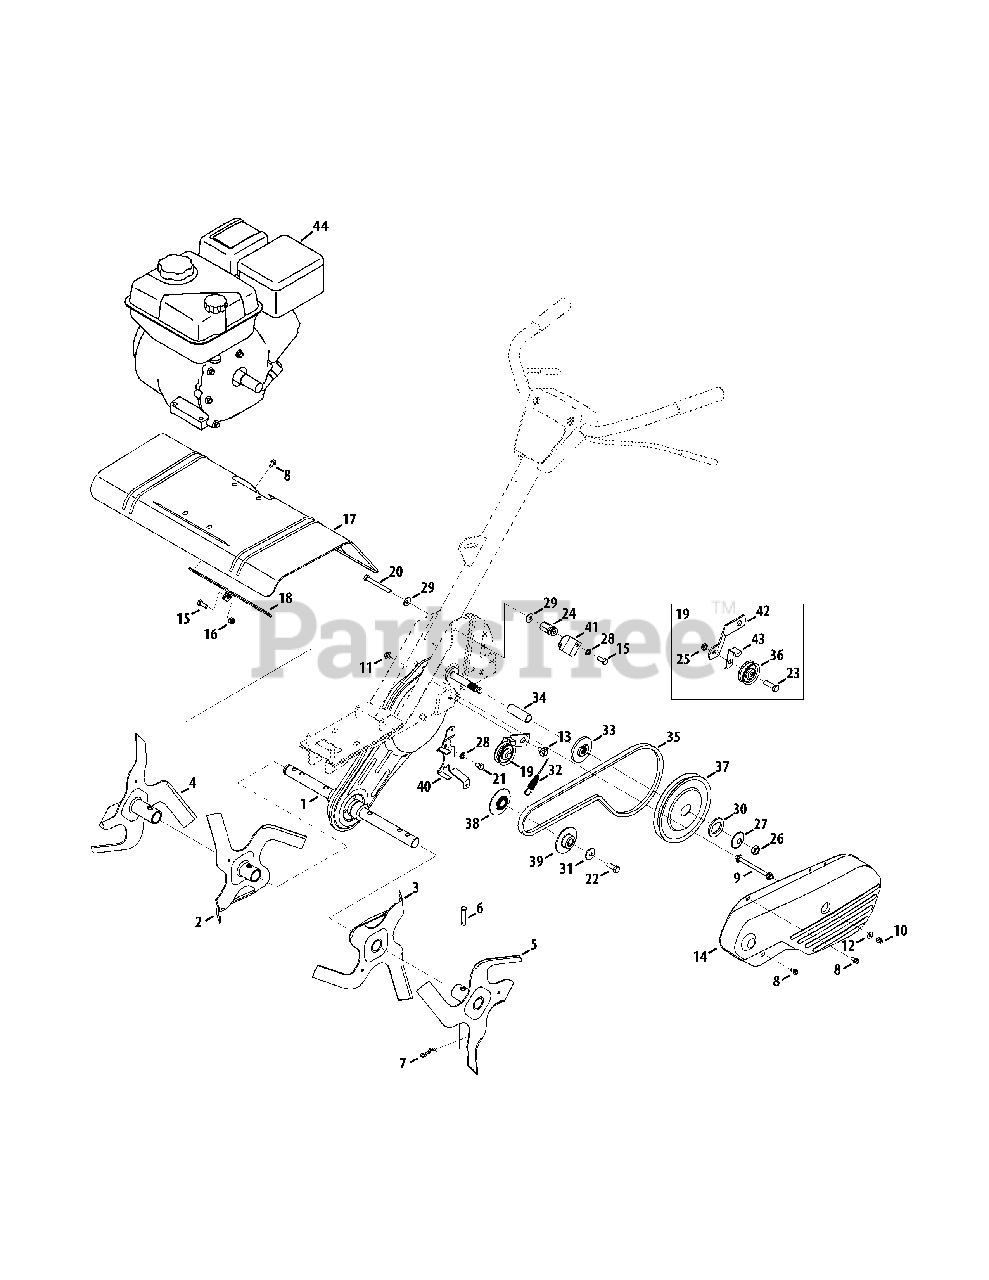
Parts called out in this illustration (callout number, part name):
1	Chain Case Assembly
2	Inner Tine Assembly, RH
3	Inner Tine Assembly, LH
4	Outer Tine Assembly, RH
5	Outer Tine Assembly, LH
6	Clevis Pin, .375 x 1.75
7	Bow Tie Cotter Pin
8	Screw, 1/4-20 x 0.500
9	Bolt, Belt Cover
10	Nut, 1/4-28, Lock
11	Nut, 5/16-18, Flange Lock
12	Flat Washer, .271 x .630 x .065
13	Shoulder Screw, .560 x .165 5/16-18
14	Belt Cover
15	Hex Head Screw, 5/16-18 x .75
16	Nut, 5/16-18, Flange Lock
17	Tine Shield
18	Bracket, Tine Shield
19	Idler Bracket Assembly
20	Hex Head Screw, 5/16-18 x 3.00
21	Hex Head Screw, 5/16-24 x .625
22	Hex Head Screw, 3/8-24 x 1.00
23	Hex Head Screw, 3/8-16 x 1.25
24	Hex Nut, 5/16-18
25	Jamlock Nut, 3/8-16
26	Nut, 1/2-20, Jam
27	Washer, .531 x 1.62 x .045
28	Lock Washer, 5/16
29	Bell Washer, .340 x .872 x .060
30	Flat Washer, 1.26 x 1.87 x .150
31	Bell Washer, .396 x 1.140 x .095
32	Forward Clutch Cable
33	Pulley Adaptor
34	Spacer, .64 ID x 2.4
35	Belt, 4L x 41.9 LG
36	Pulley 1.88 OD
37	Pulley 6.00 OD
38	Inner Engine Pulley
39	Outer Engine Pulley
40	Belt Keeper Bracket
41	Cable Guide Bracket
42	Idler Bracket
43	Belt Keeper
